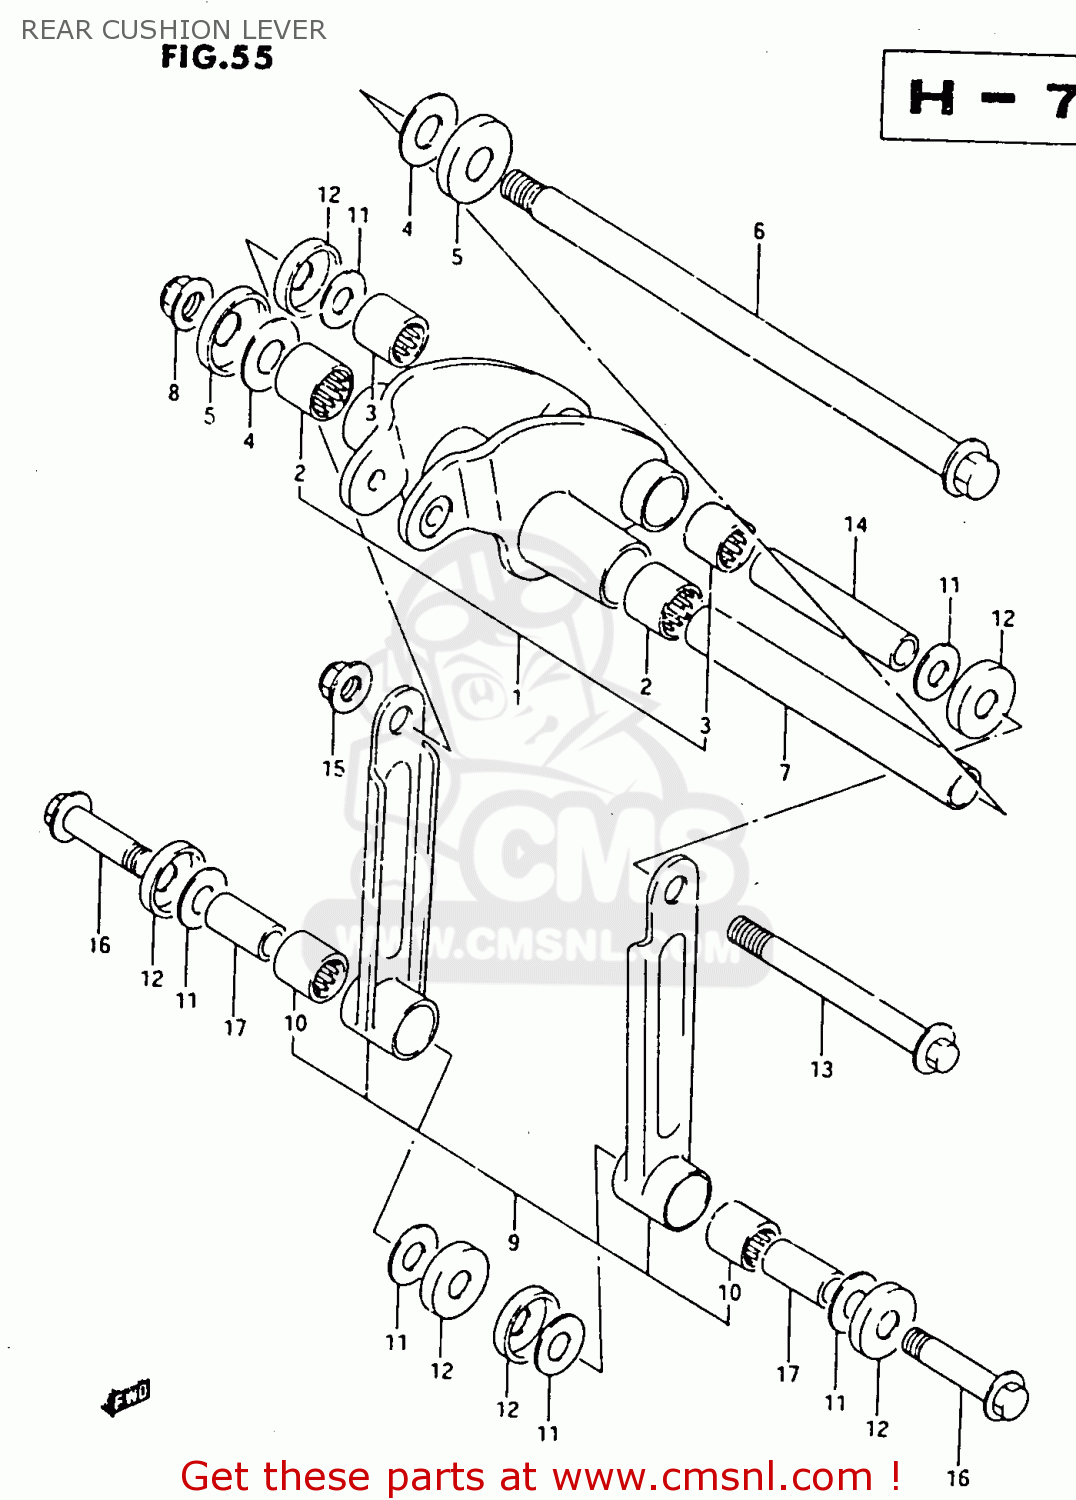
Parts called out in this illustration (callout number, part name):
1	LEVER SET,REAR CUSHION
2	BEARING(20X27X25)
3	ROLLER BEARING (17X24X25)
4	WASHER
5	SEAL,REAR CUSHION LEVER
6	SHAFT,REAR CUSHION LEVER
7	SPACER,RR CUSHION LEVER
8	NUT 12MM
9	ROD SET,REAR CUSHION
10	ROLLER BEARING (17X24X25)
11	WASHER
12	COVER,RR SWGARM DUST SEAL
13	BOLT,REAR CUSHION ROD
14	SPACER,RR CUSHION ROD UPR
15	NUT 12MM
16	RING,BEARING STOPPER
17	SPACER,RR CUSHION ROD LWR
